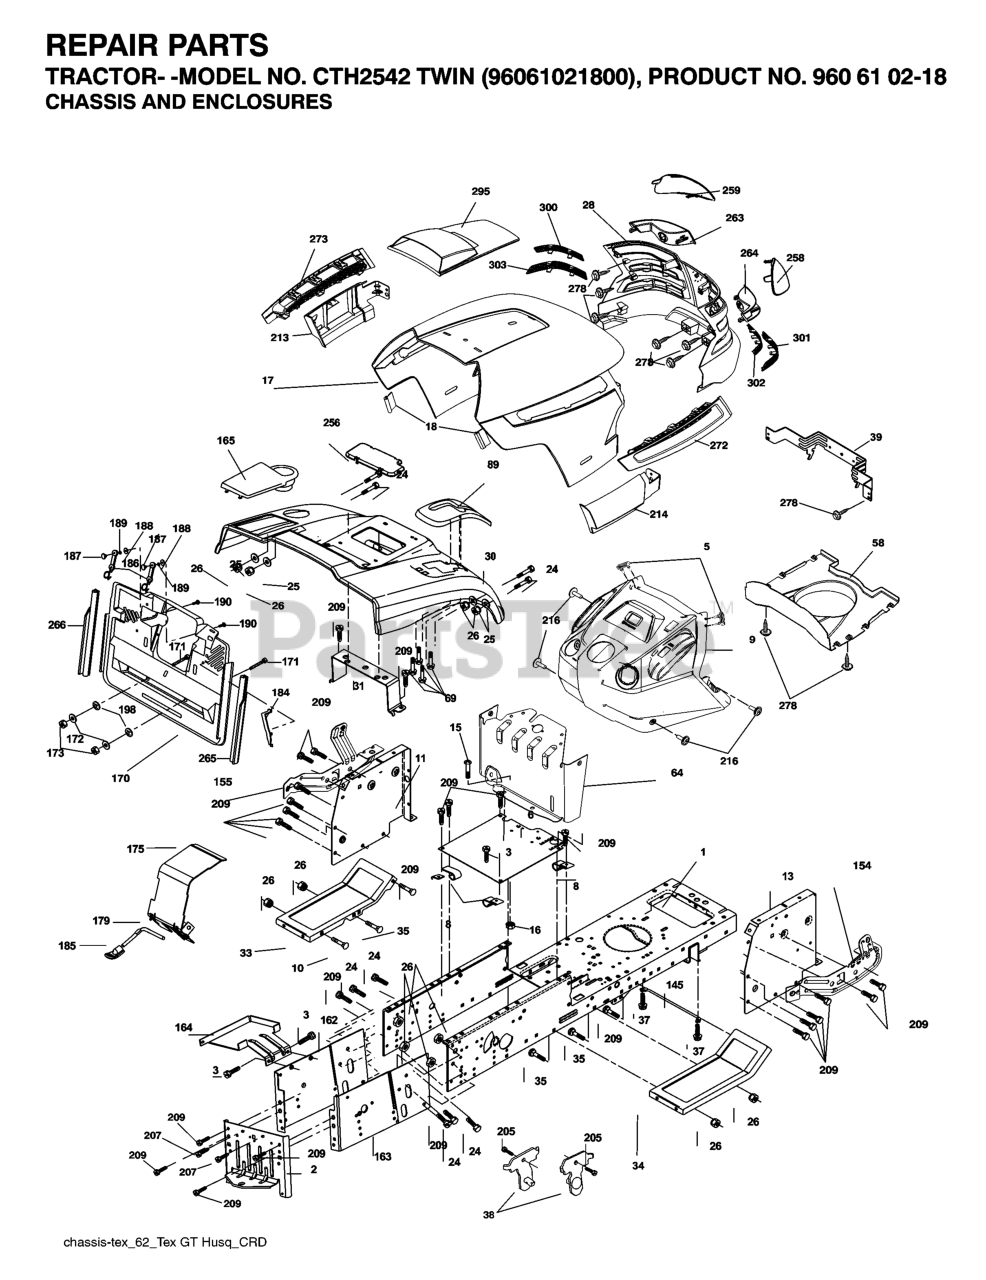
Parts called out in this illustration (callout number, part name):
2	DRAWBAR
3	SCREW 3/8-16X3/4
5	BUMPER DASH
6	PLATE
8	CLIP,INSULATOR
10	BOLT D
11	PANEL DASH LH
13	PANEL DASH RH
15	Screw, Machine, Truss Head 5/16-18 UNC x 3/4
16	NUT
17	HOOD
18	BUMPER.HOOD.TEX.HUSQVARNA
25	WASHER
26	NUT
28	GRILL.ASM.HUSQ.TG/CRD.W/TRIM
30	CONSOLE.CRD.AUTO.GRY
31	BRACKET SUPPORT FENDER
33	FOOTREST PNT LH
34	FOOTREST PNT RH
37	Screw 5/16-18 x 1/2 Hex, Self Tapping 5/16-18 x 1/2
38	BRACKET ASM PIVOT MOWER REAR
39	HOOD PIVOT BRACKET
58	AIR.DUCT.HOOD.TEX.GT.HUSQ
69	SCREW.HI-LO.CONSOLE
89	CONSOLE.CRD.AUTO.GREY.2005
145	ROD PIVOT CHASSIS/HOOD
162	BRACKET
163	BRACKET EXTEN CHASSIS RH CRD
165	RP.COVER.BATTERY.CRD.GREY
172	WASHER
175	DOOR TRAP
179	ROD PIVOT FBI
184	BRACKET.ACTUATOR.BAGGER.SRD
186	LATCH ASSY
187	WELDNUT
189	LOCKWASHER #10
190	SCREW
207	SCREW, 5/16-18 X 1/2
209	SCREW, 3/8-16X3/4
213	SKIRT.HOOD.SIDE.HUSQ.LH.GREY
214	SKIRT.HOOD.SIDE.HUSQ.RH.GREY
216	SCREW 14-20 X 5/8
256	COVER FENDER CRD
258	LENS.RH.TEX.GT.HUSQ.CL
259	LENS.LH.TEX.GT.HUSQ.CL
263	BEZEL.RH.TEX.GT.HUSQ
264	BEZEL.LH.TEX.GT.HUSQ
265	SEALING
266	SEALING
272	VENT.SIDE.HOOD.HUSQ.RH.GREY
273	VENT.SIDE.HOOD.HUSQ.LH.GRAY
278	SCREW
295	VENT.ASM.HOOD.TOP.TEX.
300	INSERT.HEX.GRILL.HUSQ.
301	INSERT.HEX.GRILL.HUSQ.GREY
302	INSERT.HEX.GRILL.HUSQ.
303	INSERT.HEX.GRILL.HUSQ.
